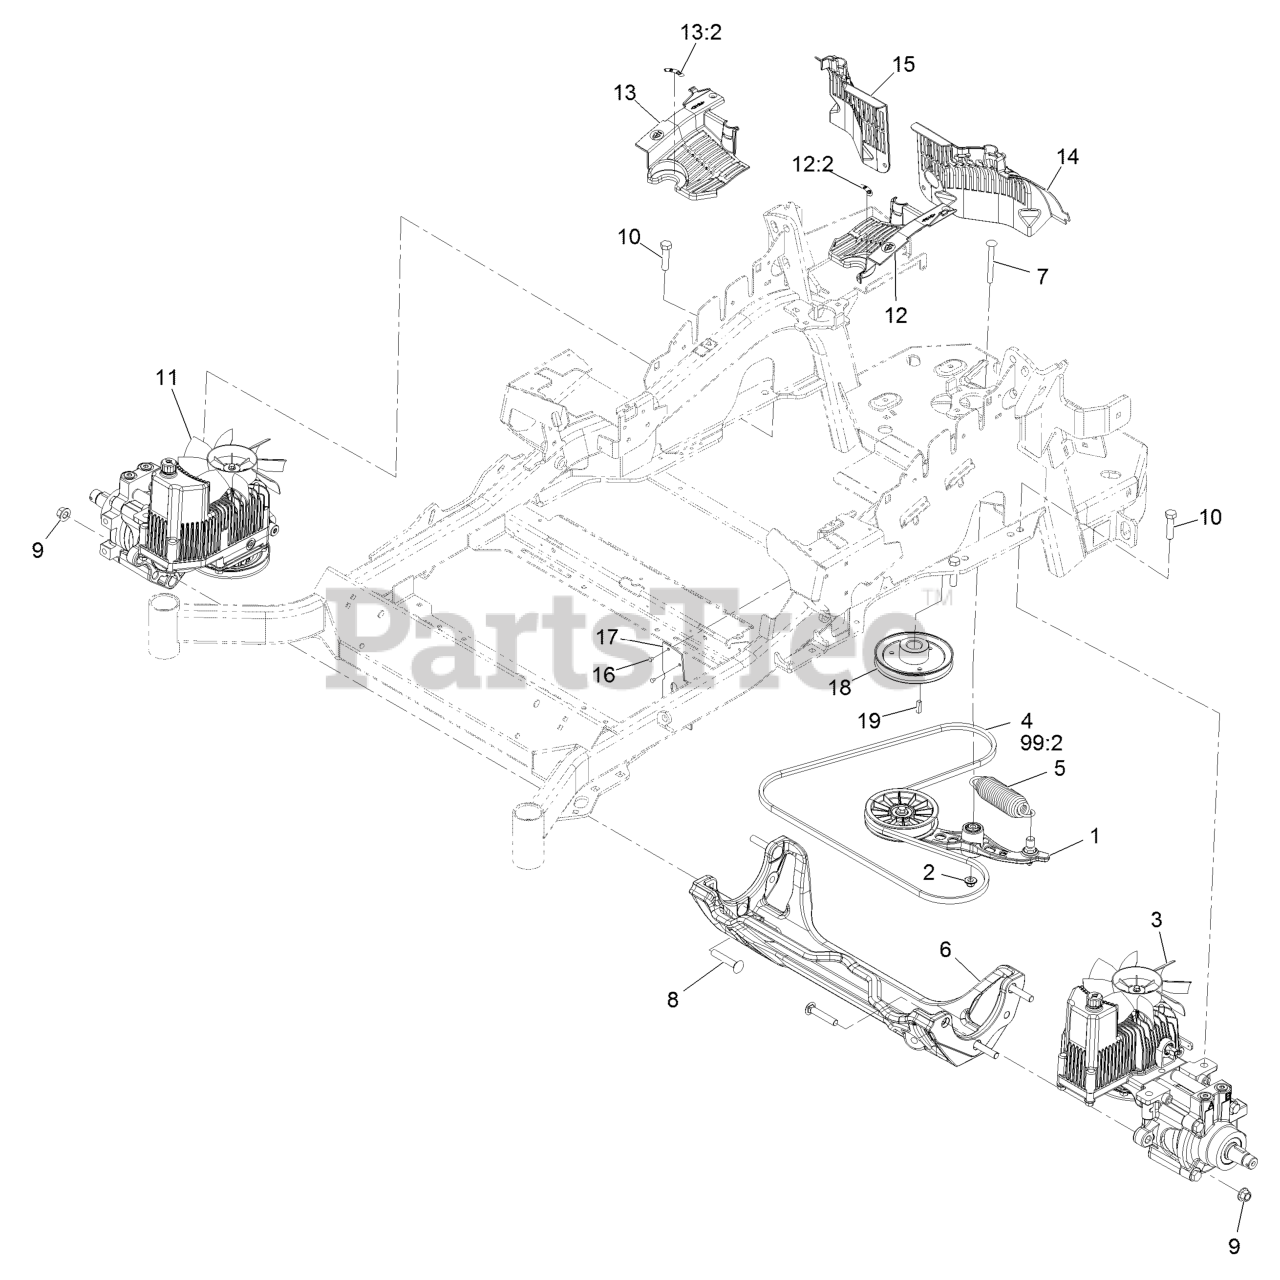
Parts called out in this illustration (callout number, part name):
1	PUMP IDLER ASM
2	Nut-Nyloc 3/8-16 Flg
3	LH HYDRO ASM (12CC W/ SHO
4	BELT
5	SPRING-EXTENSION
6	CRADLE-HYDRO
7	BOLT-SHOULDER, CARRIAGE 3/8-16 X 3 1/2
8	SCREW-CARR
9	Nut-Lock 1/2-13
10	SCREW-HH
11	RH HYDRO ASM (12CC W/ SHO
12	LH HYDRO GUARD ASM
12:2	DECAL-OIL, HYDRO
13	RH HYDRO GUARD ASM
13:2	DECAL-OIL, HYDRO
14	GUARD-HYDRO, REAR (LH)
15	GUARD-HYDRO, REAR (RH)
16	RIVET-POP
17	DEFLECTOR-AIR FLOW
18	SHEAVE
99:1	BOTTLE-OIL, 32OZ HYDRAULIC
99:2	BELT
